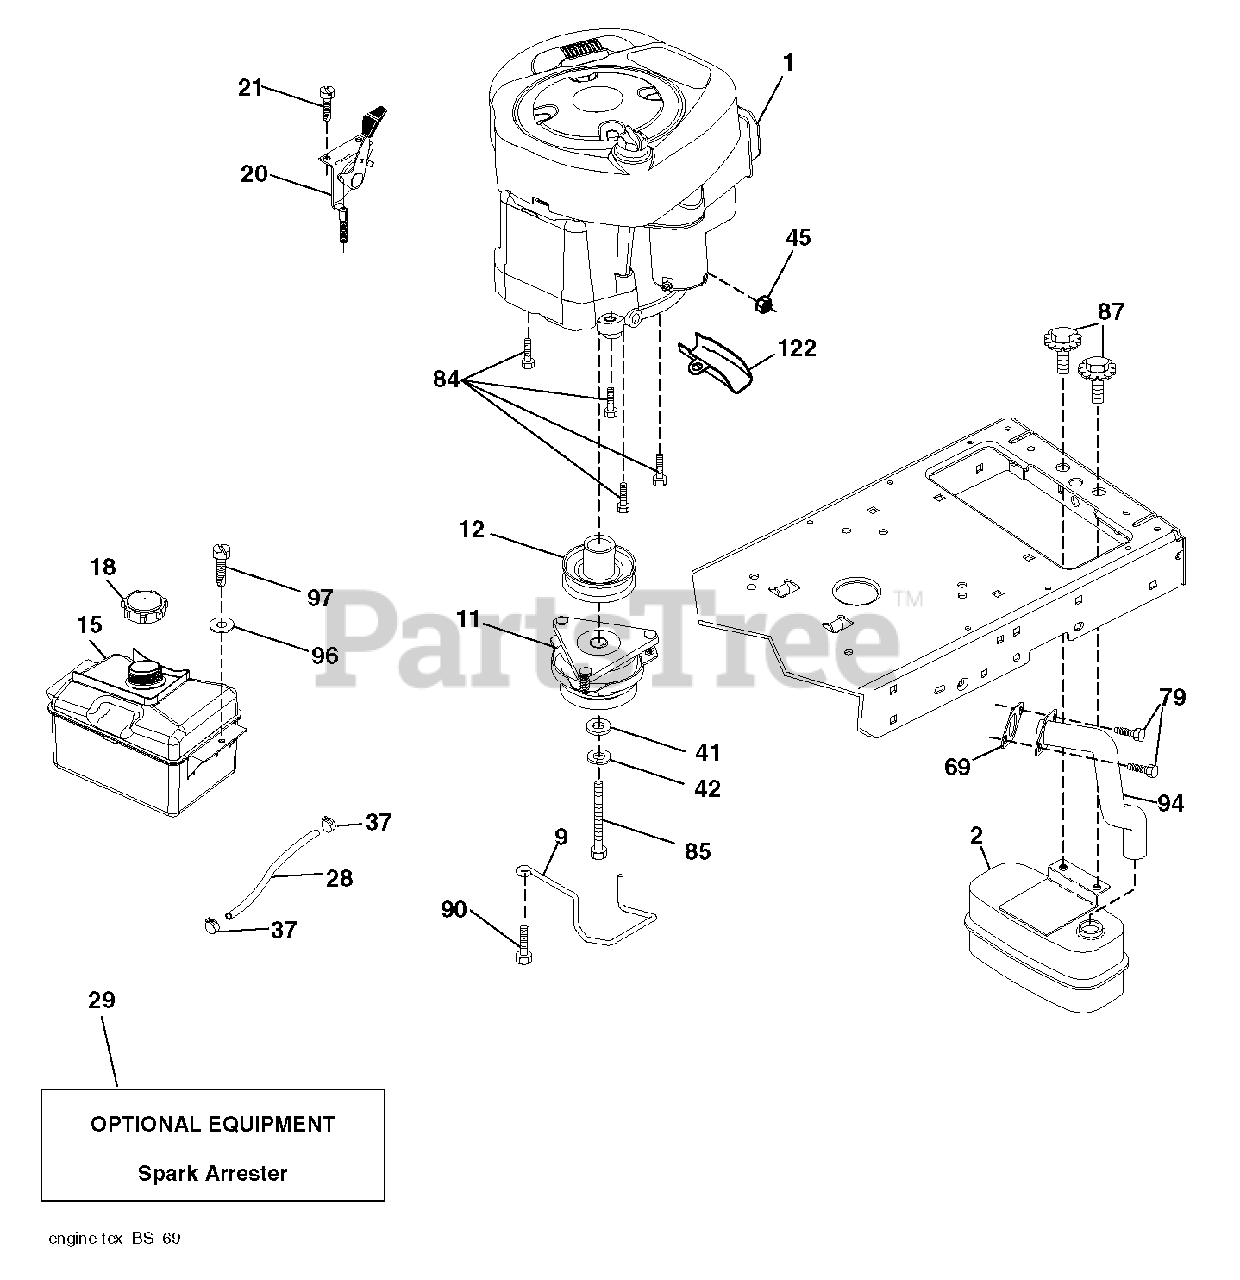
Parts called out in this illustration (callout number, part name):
2	MUFFLER.SINGLE.CYL.KOHL/B&S
9	KEEPER.BELT.ENGINE.4.2
11	CLUTCH.ELECTRIC.LT.48"*
12	PULLEY.ENGINE.TUFFTORQ
15	RP TANK FUEL FRT 1.5 GAL
18	CAP ASM.FUEL.2.25"FR.
20	CONTROL.TH/CK.COBRA.BS.EE.421
21	SCREW.#10 X 0.750.BOS
28	LINE.FUEL.20
29	KIT.SPARK ARRESTOR 794945 B&S
37	HOSE CLAMP
42	LOCKWASHER
45	NUT
69	REPL BY 532 27 22-93
79	SCREW.SOCKET HD.5/16-1
84	SCREW.3/8-16
85	BOLT HEX 7/16-20X4-1/4"
87	BOLT, 5/16-18 X 1 3/4
90	SCREW 3/8-16X1
94	EXHAUST.TUBE.B&S.
97	SCREW HEXWSHR 1/4-20X3/4
122	EXTENSION DRAIN OIL
